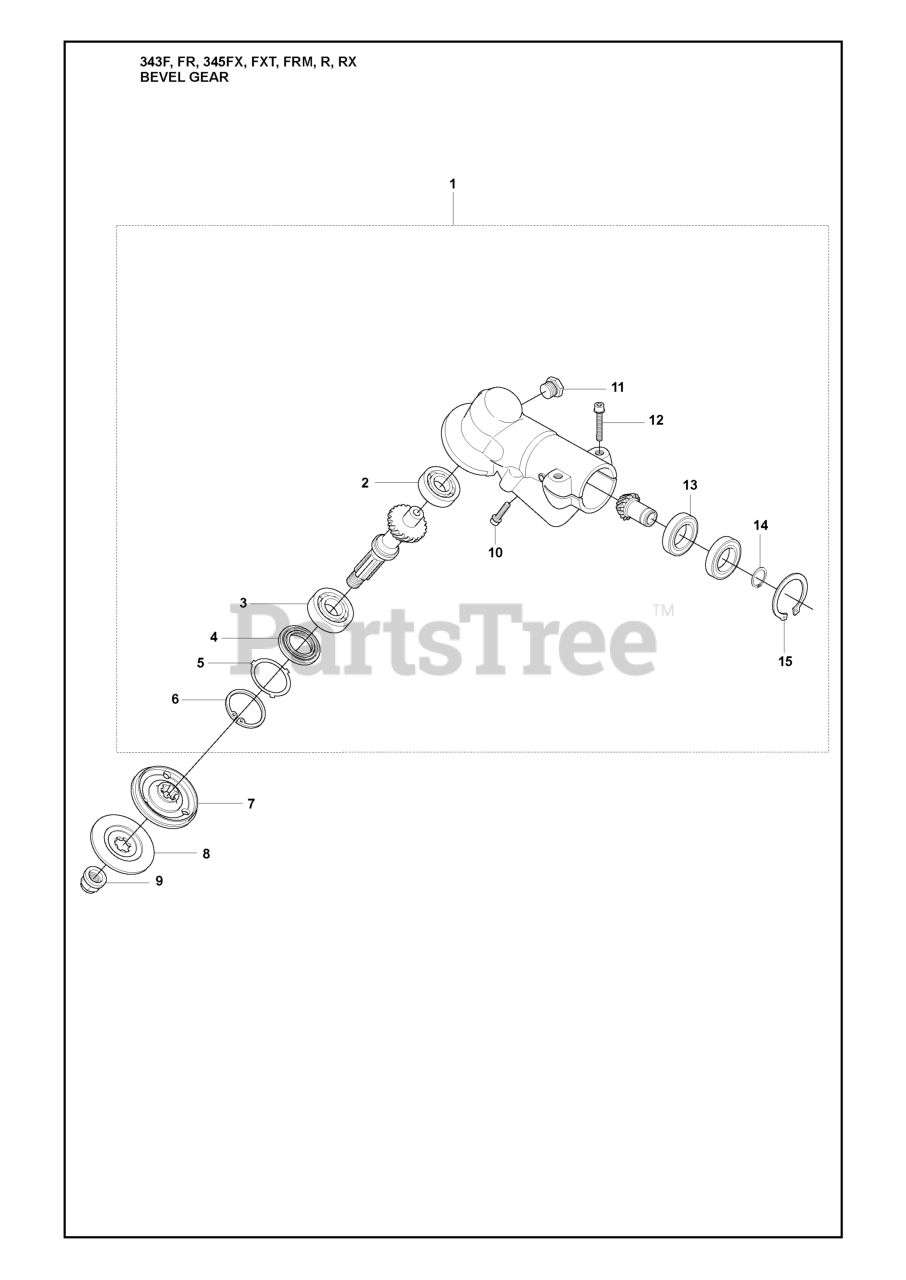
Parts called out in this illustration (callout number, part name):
1	GEAR ASSY
2	BALL BEARING
3	BALL BEARING
6	RETAINING RING SGH 35
7	DRIVER
8	SUPPORT FLANGE
13	BALL BEARING
14	RETAINING RING SGA 15
15	RETAINING RING
